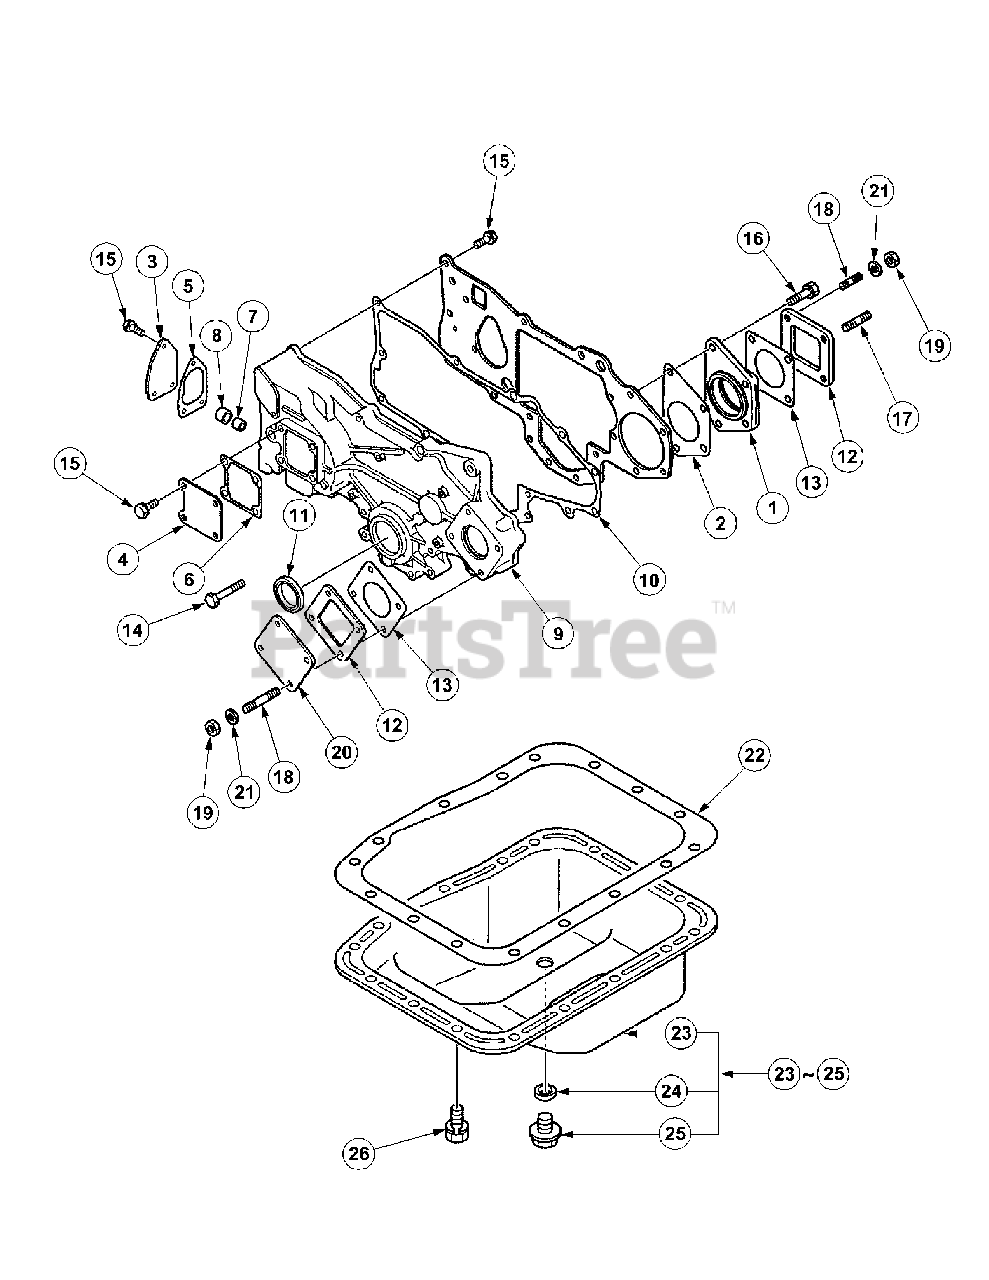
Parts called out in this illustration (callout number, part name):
1	Housing,Gear
2	Gasket,Housing
3	Cover,Governor
4	Cover,Gear Case
5	Gasket,Governor
7	Bearing,Needle
8	Bearing,Needle
9	Case,Gear
11	Seal,Front Oil
12	Cover,Oil Pump
15	Bolt,w/Washer
16	Bolt,w/Washer
20	Cover,Oil Pump
21	Washer,Spring
23	Pan Sub Assy
26	Bolt,w/Washer
